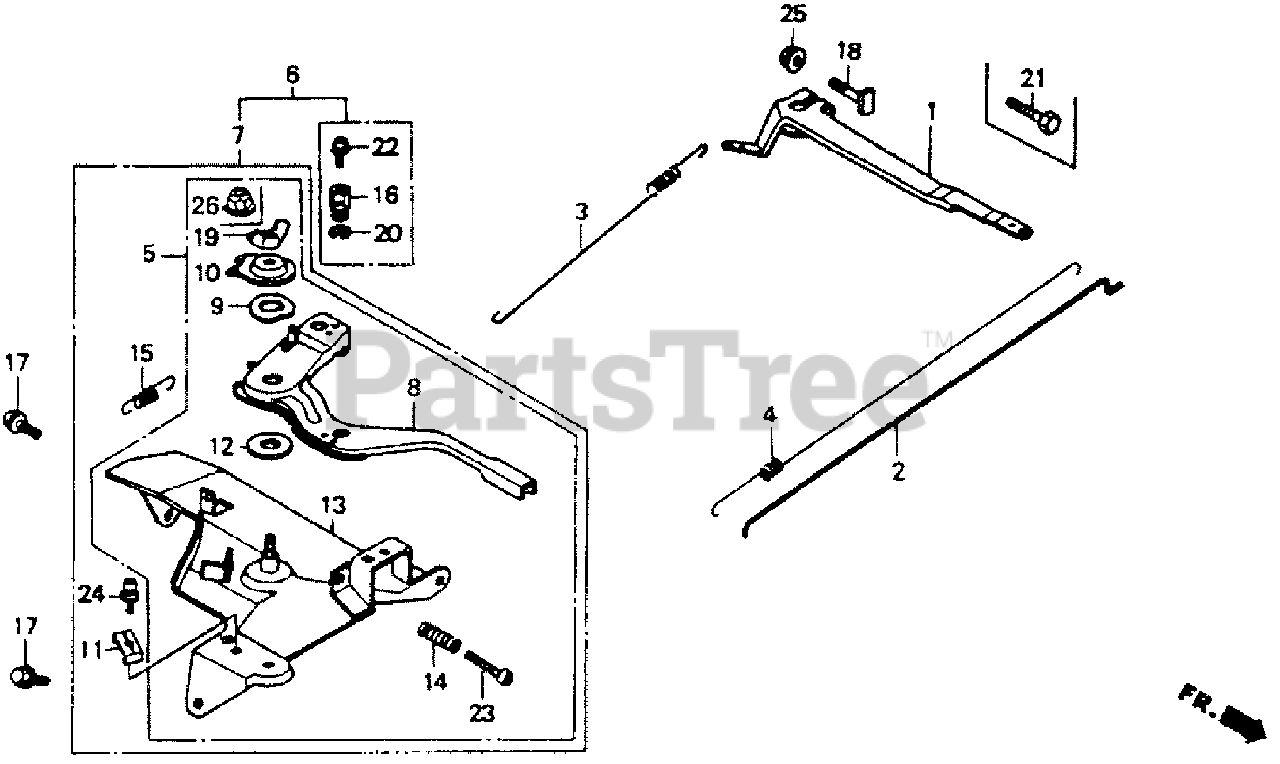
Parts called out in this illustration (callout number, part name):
1	ARM, GOVERNOR
2	ROD, GOVERNOR
3	SPRING, GOVERNOR
4	SPRING, THROTTLE RETURN
7	CONTROL ASSY. (REMOTE)
8	LEVER, CONTROL
9	SPRING, LEVER
10	WASHER, CONTROL LEVER
11	HOLDER, CABLE
12	SPACER, CONTROL LEVER
13	BASE, CONTROL
14	SPRING, CONTROL ADJUSTING
15	SPRING, CABLE RETURN
17	BOLT, FLANGE (6X12) (CT200)
18	BOLT, GOVERNOR ARM
19	WINGNUT (6MM)
21	BOLT, HEX. (6X22)
23	SCREW, PAN (5X28)
24	SCREW, PAN (5X16)
24	SCREW-WASHER (5X16)
25	NUT, FLANGE (6MM)
NI	NUT, SELF-LOCK (6MM)
